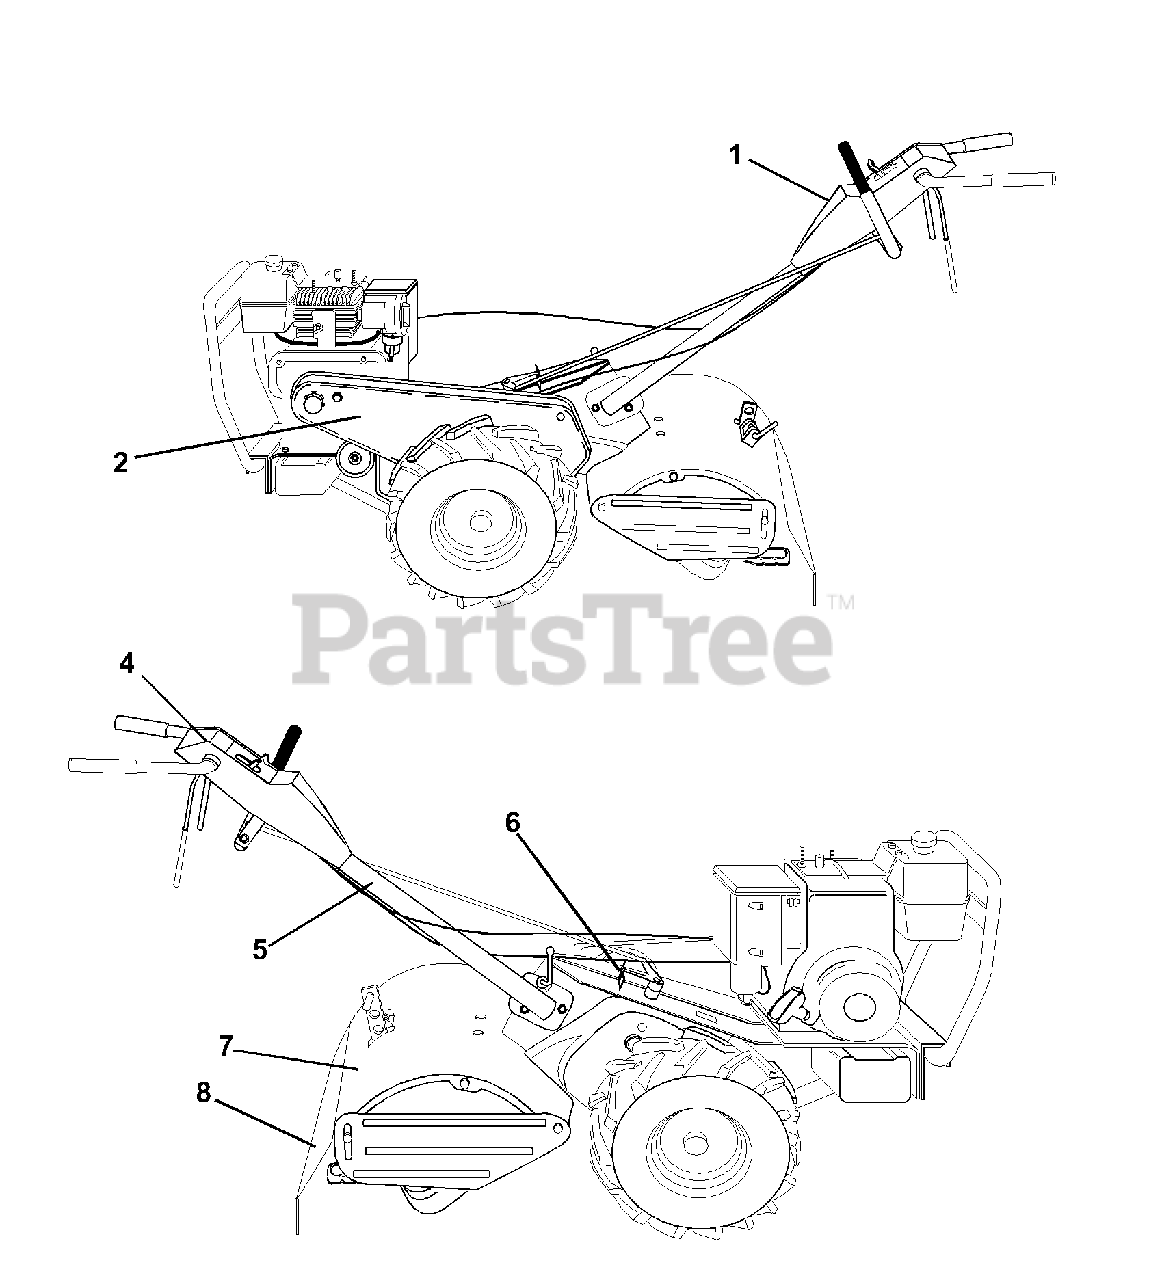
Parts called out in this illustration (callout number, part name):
1	Decal, Logo
2	Decal, Logo
4	Decal, Instruction, Tilling
5	Decal, Hand Placement
6	Decal, Shift Indicator
7	Decal, Caution
8	Decal, Warning, Rotating Tines
